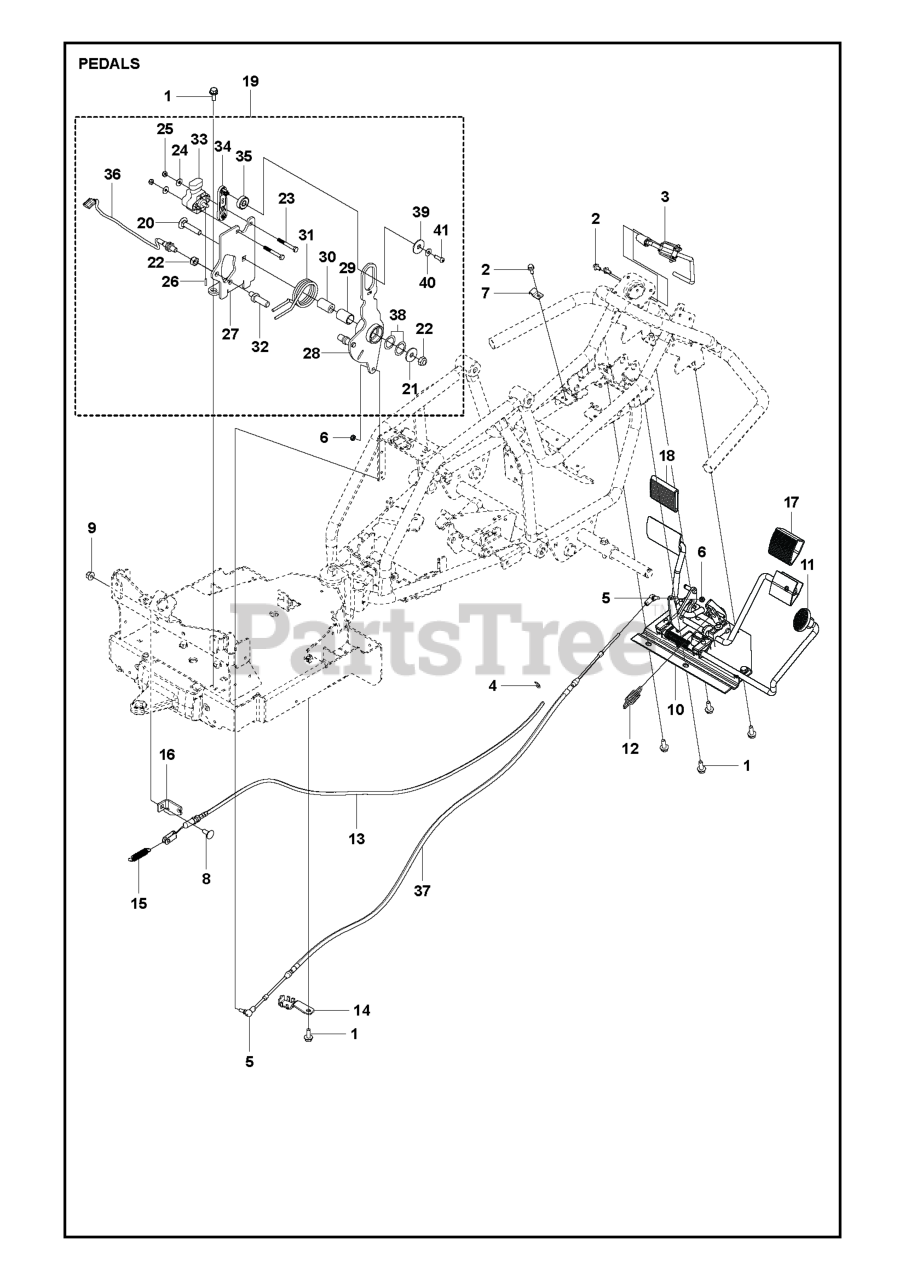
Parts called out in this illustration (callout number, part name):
5	CONNECTOR, BALL JOINT
6	LOCKNUT M6
9	NUT FLANGE
11	KNOB, THREADED
17	PEDAL RUBBER
18	PEDAL RUBBER L = 102MM
22	LOCKNUT M8
23	SCREW M6S 5X40
25	LOCKNUT M5
35	BALL BEARING
37	CONTROL CABLE
